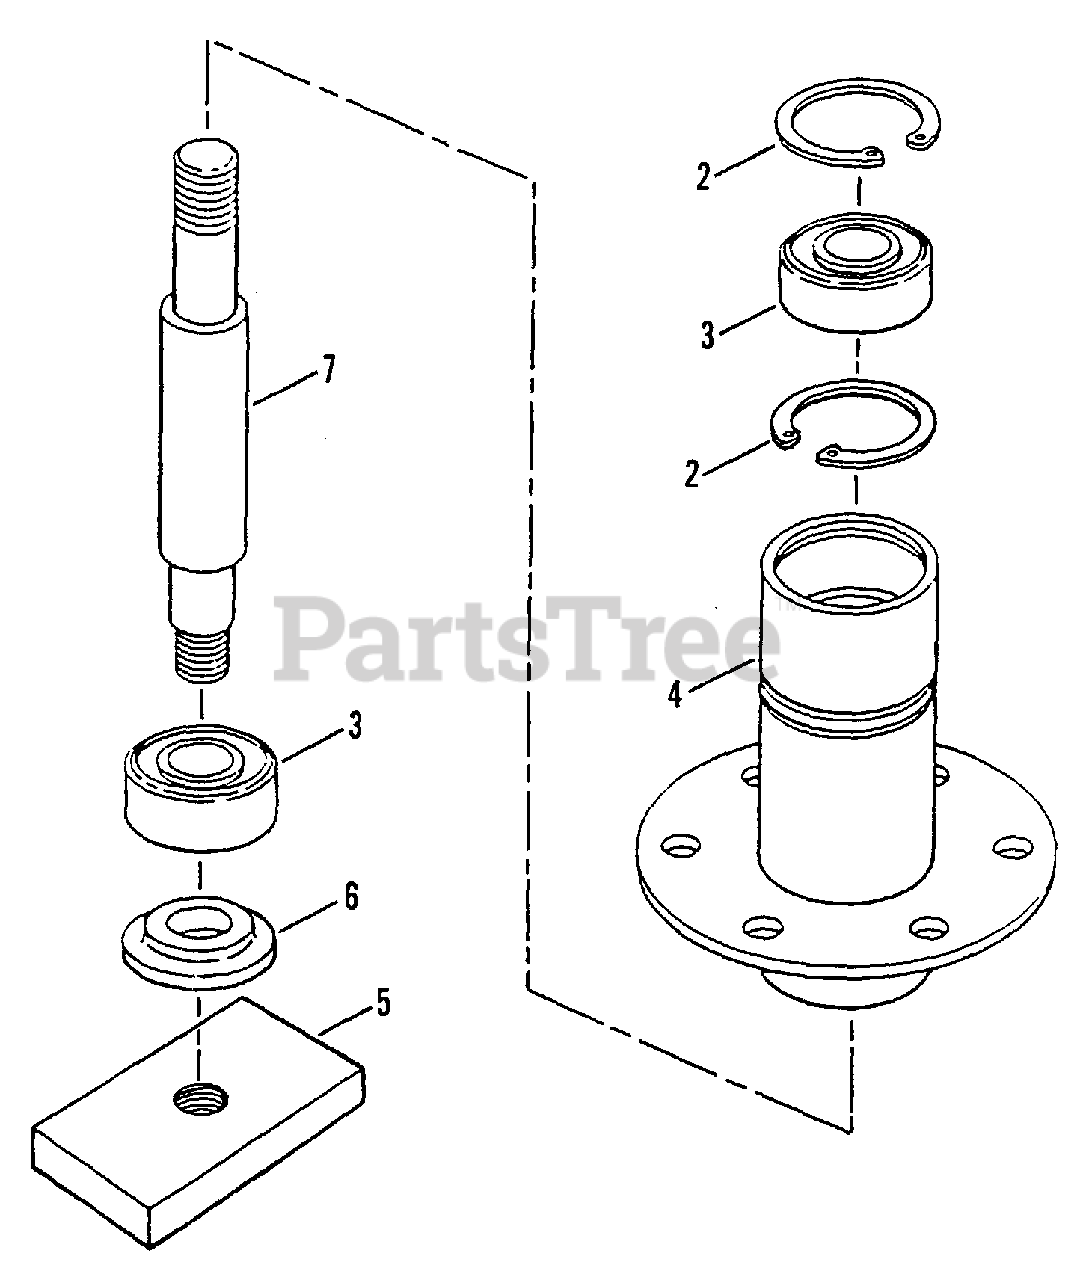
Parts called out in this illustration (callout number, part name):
2	RING, External Retaining 1-3/4"
3	BEARING, Spindle
4	HOUSING, Spindle
5	HOLDER, Blade
6	WASHER, Spindle
7	SPINDLE, 6.5" Long
